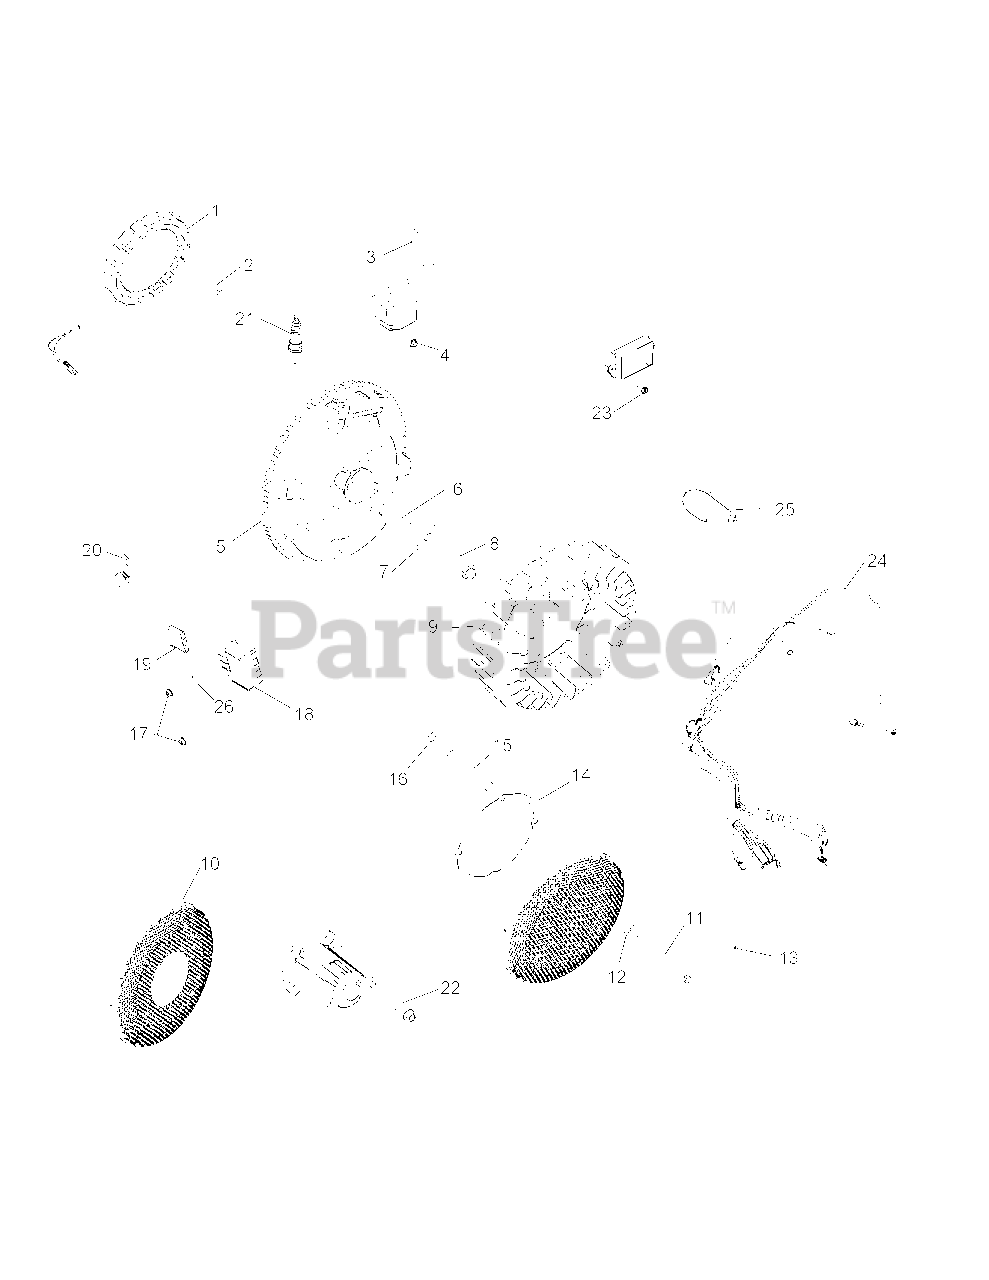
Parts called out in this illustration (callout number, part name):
1	Kit, 25 Amp Stator Assembly
1	Kit, 25 Amp Conversion
2	Thread Forming Screw
3	Module Ignition
4	Thread Forming Screw
6	Key, 3/16 x 5/8
7	Flat Washer, 13/32
8	Flange Screw, M10 x 1.5 x 45
11	Cap Screw, M6 x 1.0 x 99.5
12	Flat Washer, 1/4 x 5/8
13	Set Screw, #10-24 X 1/4
14	Support Ring
16	Spring Washer, 10 MM
17	Hex Flange Hi-Lo Screw
18	Regulator/Rectifier
20	Cable Clip
21	Spark Plug (Std.)
22	Flange Screw, M8 x 1.25 x 45
23	Washer Head Tap Screw, #8-18 x 1/2
24	Wiring Harness Assembly
